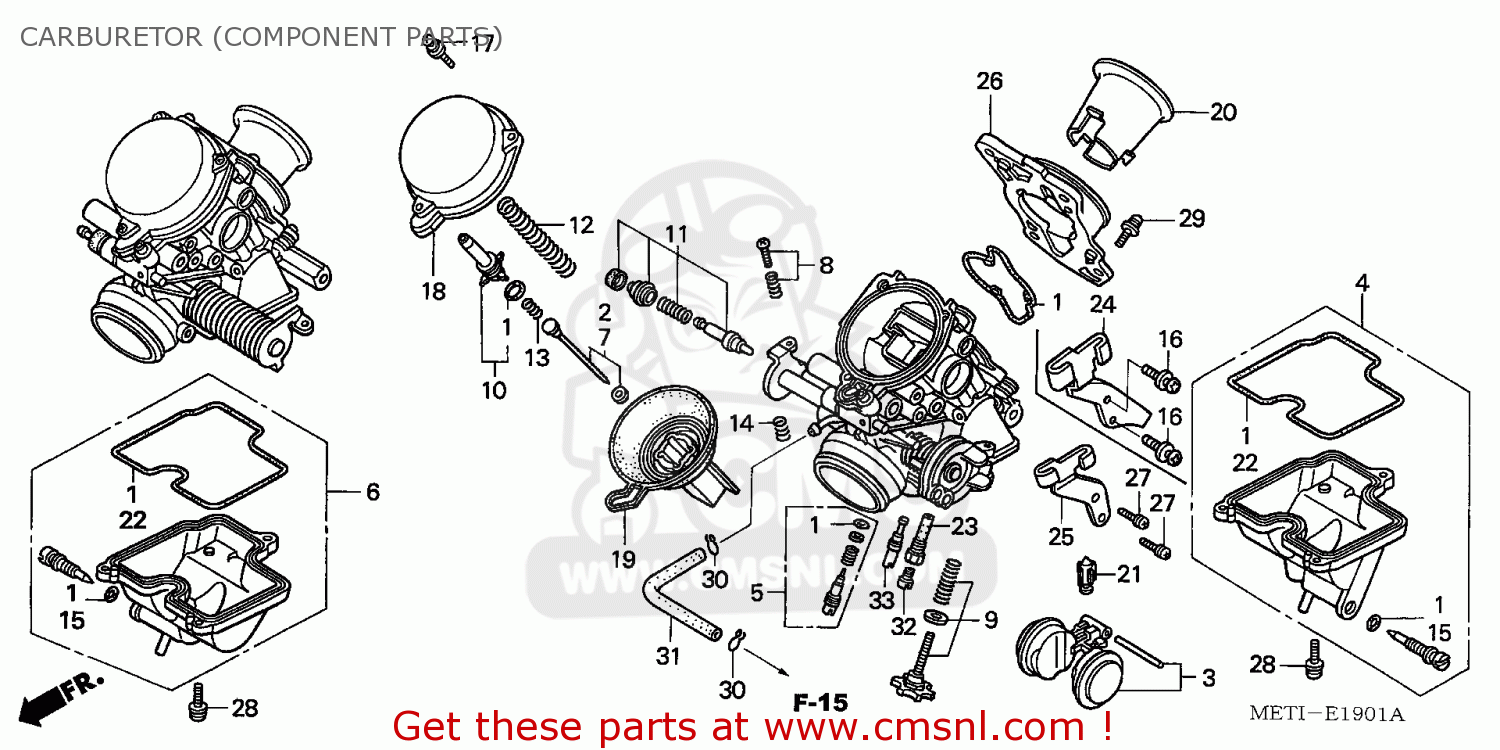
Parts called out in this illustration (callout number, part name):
1	GASKET SET,A
2	JET NEEDLE SET
3	FLOAT SET
4	CHAMBER SET,FLOAT
5	SCREW SET
6	CHAMBER SET,FLOAT
7	JET NEEDLE SET
8	SCREW SET
9	SCREW SET
10	PLATE SET,VALVE
11	STARTER VALVE SET
12	SPG,COMPRESSION C
13	SPG,COMPRESSION,C
14	SPG,COMPRESSION,C
15	O-RING,1.3X4.3
17	SCREW,PAN
18	TOP
19	PISTON COMP.,VACU
20	FUNNEL,AIR .
21	VALVE COMP,FLOAT
22	GASKET,FLOAT CHAM
23	HOLDER,NEEDLE JET
25	WIRE STAY
26	PLATE,FUNNEL SETT
27	SCREW-WASHER 5X10
28	SCREW-WASHER,5X16
29	SCREW-WASHER,4X14
30	CLIP B7,TUBE
31	TUBE,3.5X180
32	JET,MAIN,#128
33	JET,SLOW,#38
